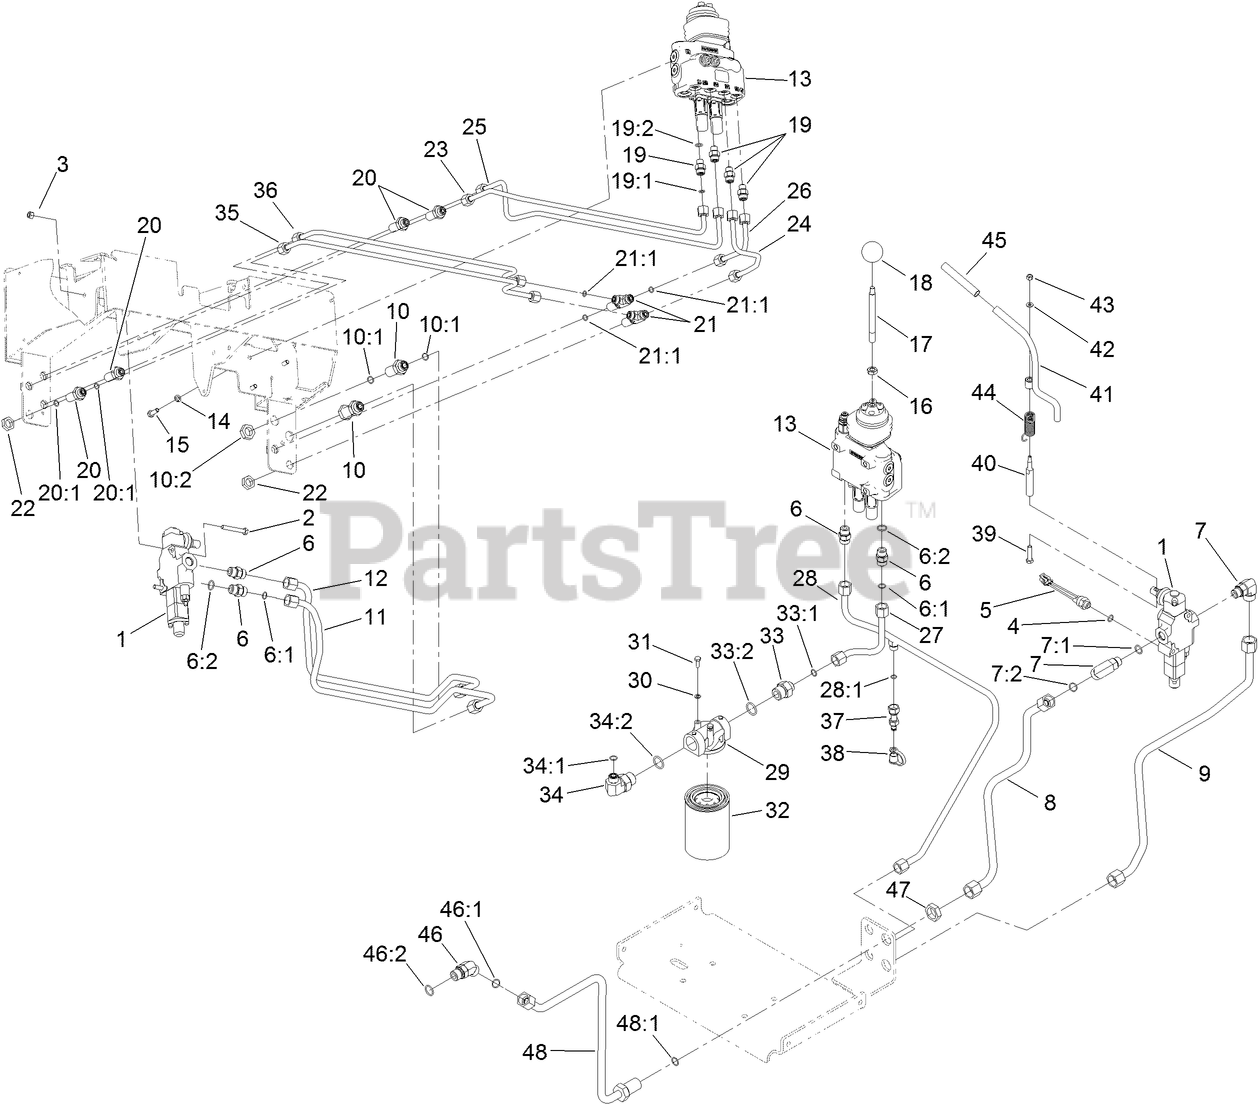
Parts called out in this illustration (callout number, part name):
1	1 SPOOL VALVE ASM
2	SCREW-HH
3	NUT-LOCK, NI
4	O-RING
5	SWITCH-BALL
6	FITTING-STRAIGHT
6:1	O-RING
6:2	O-RING
7	Fitting-Elbow, 90 DEG
7:1	O-RING
7:2	O-RING
8	TUBE-HYD
9	TUBE-HYD
10	FITTING-BULKHEAD
10:1	O-RING
10:2	NUT-BULKHEAD
11	TUBE-HYD
12	TUBE-HYD
13	2 SPOOL VALVE ASM
14	WASHER-LOCK
15	SCREW-HH
17	SHAFT-HANDLE, LOADER
19	FITTING-STRAIGHT
19:1	O-RING
19:2	O-RING
20	FITTING-STRAIGHT, BULKHEAD
20:1	O-RING
21	FITTING-TEE, BULKHEAD
21:1	O-RING
22	NUT-LOCK
23	TUBE-HYD
24	TUBE-HYD
25	TUBE-HYD
26	TUBE-HYD
27	TUBE-HYD
28	HYD TUBE ASM
28:1	O-RING
29	HEAD-FILTER
30	WASHER-LOCK
31	SCREW-HH
32	FILTER-OIL
33	FITTING-STR
33:1	O-RING
33:2	O-RING
34	FITTING-HYD, 90 DEG
34:1	O-RING
34:2	O-RING
35	TUBE-HYD
36	TUBE-HYD
37	NIPPLE-TEST
38	CAP-DUST
39	SCREW
40	SPACER-HIFLO
41	LEVER-AUXILIARY
42	WASHER-FLAT
43	NUT-LOCK, NI
44	SPRING-TORSION
45	GRIP-RUBBER
46	FITTING-HYD-45
46:1	O-RING
46:2	O-RING
47	NUT-LOCK, BULKHEAD
48	HYD TUBE ASM
48:1	O-RING
